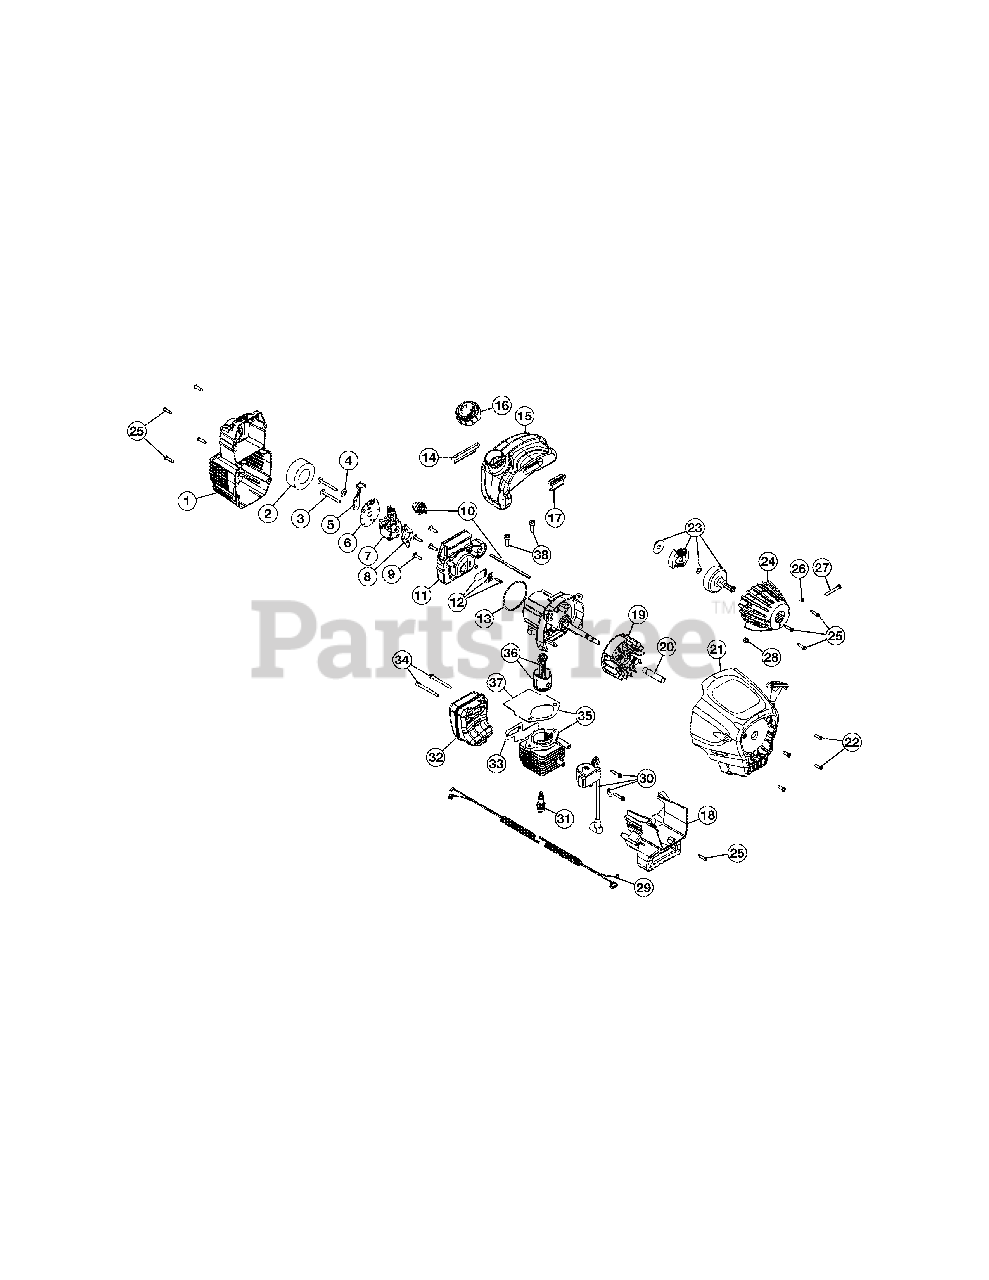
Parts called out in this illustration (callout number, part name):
1	Air Cleaner Cover Assembly (includes 2 & 25)
2	Air Cleaner Filter
3	Carburetor Mounting Screw Assembly
4	Wavey Washer
5	Choke Lever Assembly
6	Choke Plate Assembly (includes 5)
7	Carburetor Assembly (includes 8)
8	Carburetor Gasket
9	Carb Mount Screw
10	Primer & Hose Assembly
11	Carb Mount Assembly (includes 9, 12 & 13)
12	Reed Assembly
14	Rear Mounting Pad
15	Fuel Tank Assembly (includes 16)
16	Fuel Cap Assembly
17	Front Mounting Pad
18	Shroud Extension & Stand (includes 26)
19	Flywheel Assembly
21	Starter Housing Assembly (includes 22 & 25)
22	Housing Screw
23	Clutch Rotor Assembly
24	Clutch Cover Assembly (includes 25-28)
25	Cover Screw
26	Anti-Rotation Screw
27	Clamping Screw
28	Clamping Nut
29	Wire Leads and Sleeve
30	Module Assembly
32	Muffler Assembly
33	Exhaust Gasket
34	Muffler Mounting Bolts
35	Cylinder Assembly (includes 37 & 38)
36	Piston and Rod Assembly
37	Cylinder Gasket
38	Cylinder Bolt
